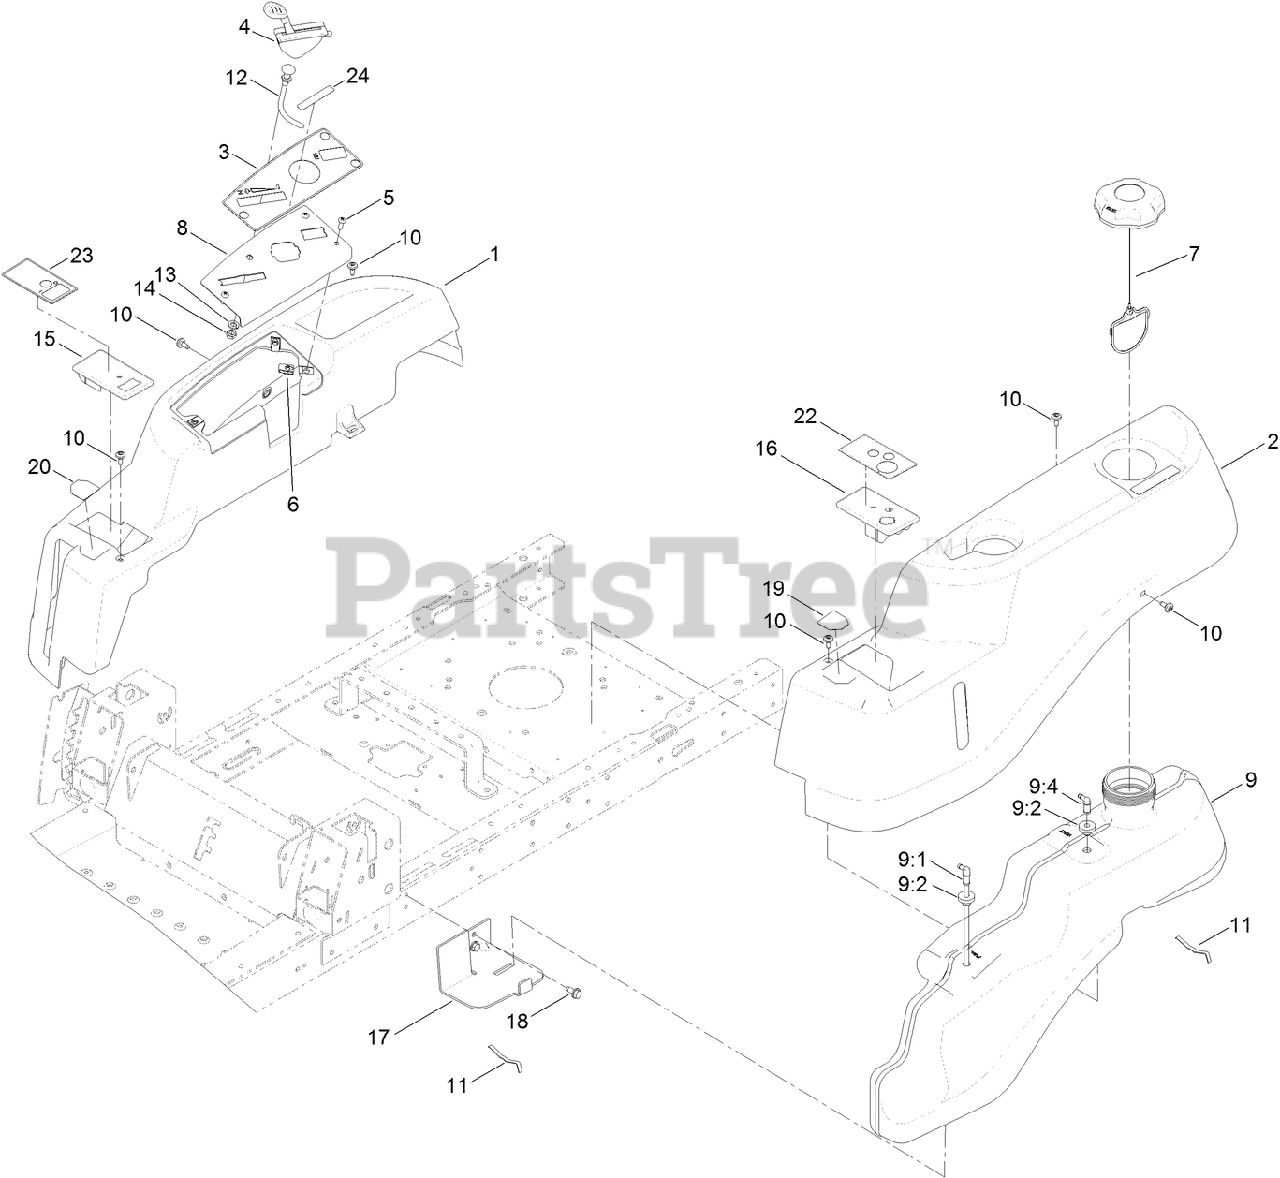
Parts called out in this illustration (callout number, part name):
1	POD-RH
2	POD-LH
3	DECAL-PANEL, CONTROL
4	CABLE-THROTTLE
5	SCREW-PRH
8	PLATE-CONTROL
9	FUEL TANK ASM
9:1	CONNECTOR-ELBOW, 90 DEG
9:2	BUSHING
9:4	FITTING-PLASTIC
10	SCREW-SHOULDER
11	SPRING
12	CABLE-CHOKE
13	WASHER-LOCK
14	NUT-HJ
15	COVER-RH
16	COVER-LH
17	SUPPORT-TANK, FRONT
18	SCREW-HWHTF
19	DECAL-NMIR
20	DECAL-CONTROL, PEDAL
22	DECAL-KEYCHOICE
23	DECAL-BRAKE, PARKING
24	DECAL-SHUTDOWN
